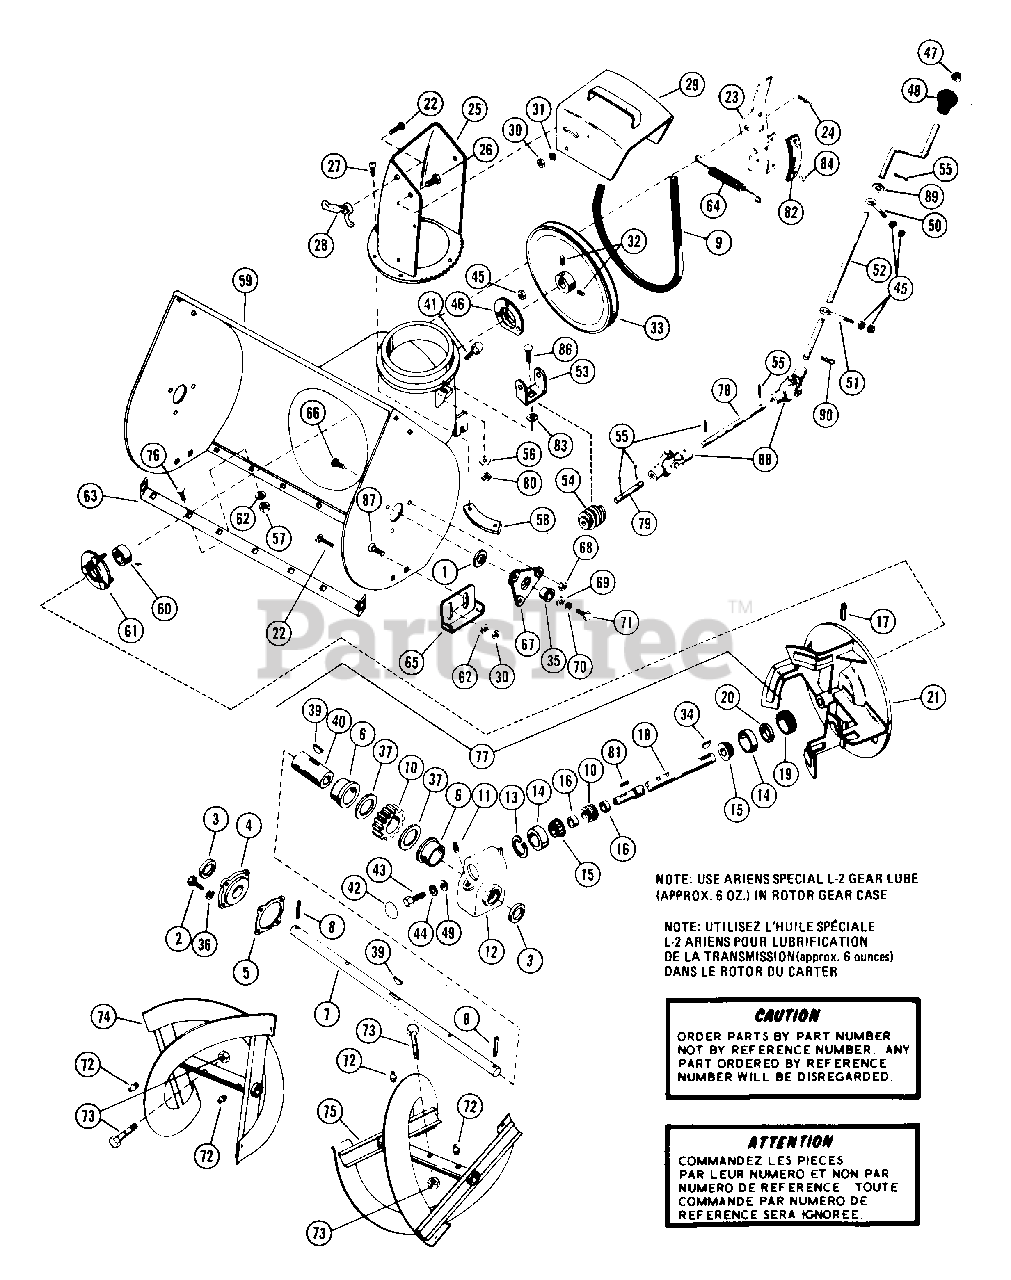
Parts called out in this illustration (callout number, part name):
1	WSHR-FL-STL 1.010X1.505X.062PL
2	BLT-SERHFWH .25-20X.75 PL
3	SEAL 1.000X1.312X.150
4	GEAR CASE FLANGE
6	BSHG-FLG 1.000X1.12X.62X1.50BR
7	FRONT GEAR SHAFT
8	PIN-ROLL .188X1.50
10	PINION & SHAFT SERVICE ASSEMBL
11	PIPE PLUG
12	CASE, GEAR - C.I.
13	RG-RTNG INT 1.781 HSG X.062
14	BRG-CUP 1.781X.475
15	BRG-CONE .750X.61
16	PIN-ROLL .313X1.38
17	PIN-ROLL .250X1.25
18	PIN-HAIR INT .08X.38X1.42 YWZC
19	ADJUSTMENT PLUG
20	SEAL .750X1.499X.225
21	FAN - 12"
22	BLT-RDHDSQNK .38-16X.75 SHT PL
25	CHUTE - DISCHARGE
26	BLT-HEX .38-16X.75 PL GR2
28	WING NUT
29	SERVICE DEFLECTOR ASSM
30	NUT-LK-CTR .375-16 GR A PL
31	WSHR-LK .375X.115 HVY PL
32	SCR-SET .32-18X.38 SKHCUPNL OH
33	PLY-? 9.0X.75
34	KEY-WDRF .188X.875X.375 SAE11
35	BSHG-FLG 1.000X1.12X.62X1.50BR
44	EYEBOLT
45	NUT-LK-CTR .250-20 PL
46	BEARING FLANGE
47	CAP, 3/8 ROD YWZC
49	BRAKE ARM ASSEMBLY
51	PARTS BAG
52	CHUTE CONTROL CRANK
53	WORM CLEVIS
54	WORM GEAR
55	PIN-ROLL .125X.75
56	WSHR-LK .313X.062
57	NUT-LK .312-18 GR A PL
58	CHUTE CLAMP
59	24 IN BLOWER HOUSING ASSY
60	BRG-BALL .750X1.750X.50
61	BEARING FLANGE
62	WSHR-FL-STL .38X.875X.083 PL
63	SCRAPER BLADE 24"
65	RUNNER
66	SCR-SLTR-SERNK .25-20X.62 PL
67	BEARING SUPPORT
68	NUT-LK-FLG .250-20 PL
69	WSHR-FL-STL .511X1.441X.125 PL
70	WSHR-LK .500X.151 HVY PL
71	BLT-HEX .50-13X1.00 PL GR2
72	SPIN DRIVE ZERK FITTING
73	SHEAR BOLT SERVICE ASSEMBLY
74	RAKE, RIGHT-24"(1ID X 15.88OD)
75	RAKE, LEFT-24"(1"ID X 15.88OD)
76	BLT-RDHDSQNK .312-18X.62 PL
77	GEAR CASE - 24" - CAST IRON
78	WSHR-FL-STL.406X.812X.065PL
79	WORM SHAFT
80	NUT-HEX .312-18
81	BEARING SPACER
82	PIN-COTR .12X1.0 PL
83	BRAKE LINING
84	RVT-TBLR .187X.375 OH ST PL
85	SG-TENS .062X.56X8.0 WLD 11
86	BLT-RDHDSQNK .31-18X.75 GR5 PL
87	PIN-ROLL .250X1.75
88	WSHR-LK-EXT .313X.030 PL
89	BLT-SCRHFWH .38-16X.75 PL
90	ROD HANGER EYEBOLT
